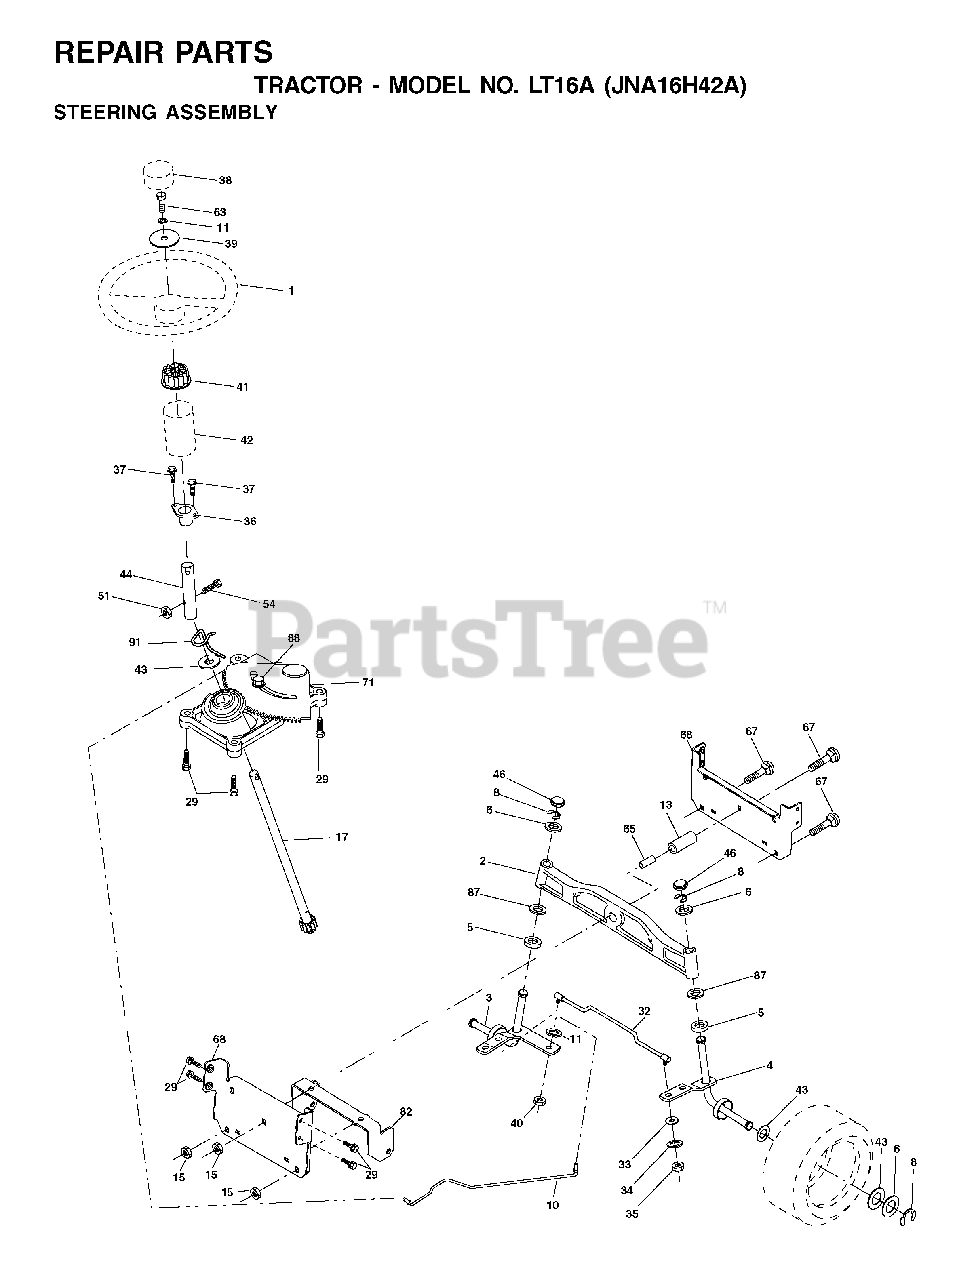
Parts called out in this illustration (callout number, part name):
2	AXLE ASM
3	SPINDLE.ASM.LH.15"TIRES
4	SPINDLE.ASM.RH.15"TIRES
8	RING CLIP
10	DRAGLINK.15".TIRES.2001
11	WASHER, LOCK 3/8
13	TUBE, PIVOT AXLE
15	NUT
17	SHAFT ASM
29	SCREW 3/8-16X3/4
33	WASHER M
34	LOCKWASHER
35	NUT, CROWNLOCK
36	BUSHING, STEERING
39	WASHER 13/32 X 2-3/8 X 12 GA
40	GRIPCO NUT
41	STEERING WHEEL ADAPTOR
42	BOOT.STEERING.SHAFT.BLACK
44	EXT SHAFT STEERING
46	CAP.SPINDLE
51	NUT.71038.31-18.HEX.NYLOCK
54	BOLT.5/16-18X1-1/4 FULL.THREAD
65	SPACER BRACE AXLE
67	BOLT
68	BRACE.AXLE.15"TIRES
71	STEERING ASM
82	BRACKET
87	WASHER, FLAT .781 X 1 1/2"
88	BOLT, SHOULDER 7/16-20
91	CLIP.STEERING
